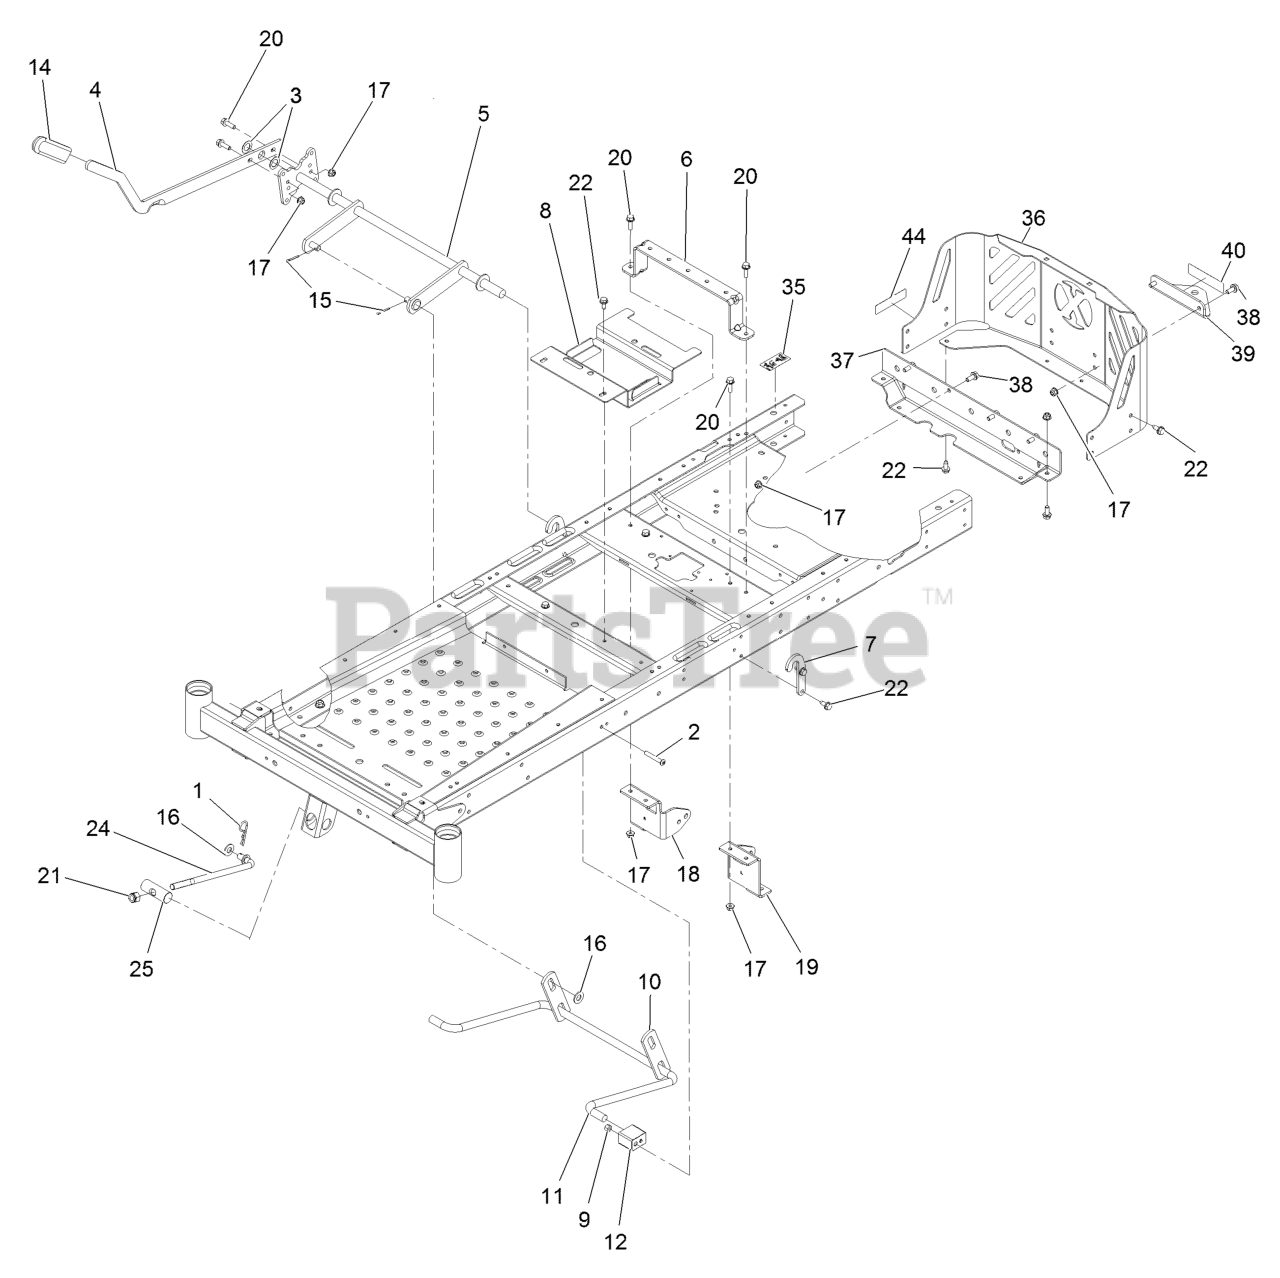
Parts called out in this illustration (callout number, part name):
1	PIN-COTTER
2	SCREW-HSBH
3	WASHER-THRUST
4	LEVER-LIFT
5	LIFT-DECK, NARROW
6	BRACE-SEAT, REAR (NARROW)
7	BRACKET-LIFT
8	BRACKET-BATTERY
9	NUT-LOCK, NI
10	LINK-LIFT
11	ARM-LIFT, REAR
12	BLOCK-PIVOT
14	GRIP-LEVER
15	PIN-COTTER
16	WASHER-FLAT
17	NUT-HF, NI
18	MOUNT-HYDRO, FRONT (RH)
19	MOUNT-HYDRO, FRONT (LH)
20	SCREW-HHF
21	NUT-HEX
22	Screw-HWH 5/16-18 X 3/4 Tf
24	ROD-MOUNT, DECK
25	PIN-PIVOT
35	DECAL-BYPASS
36	GUARD-ENGINE, NARROW
37	CROSSMEMBER-REAR, NARROW
38	SCREW-HHF
39	BRACKET-HITCH
44	DECAL-ARRESTER, SPARK
